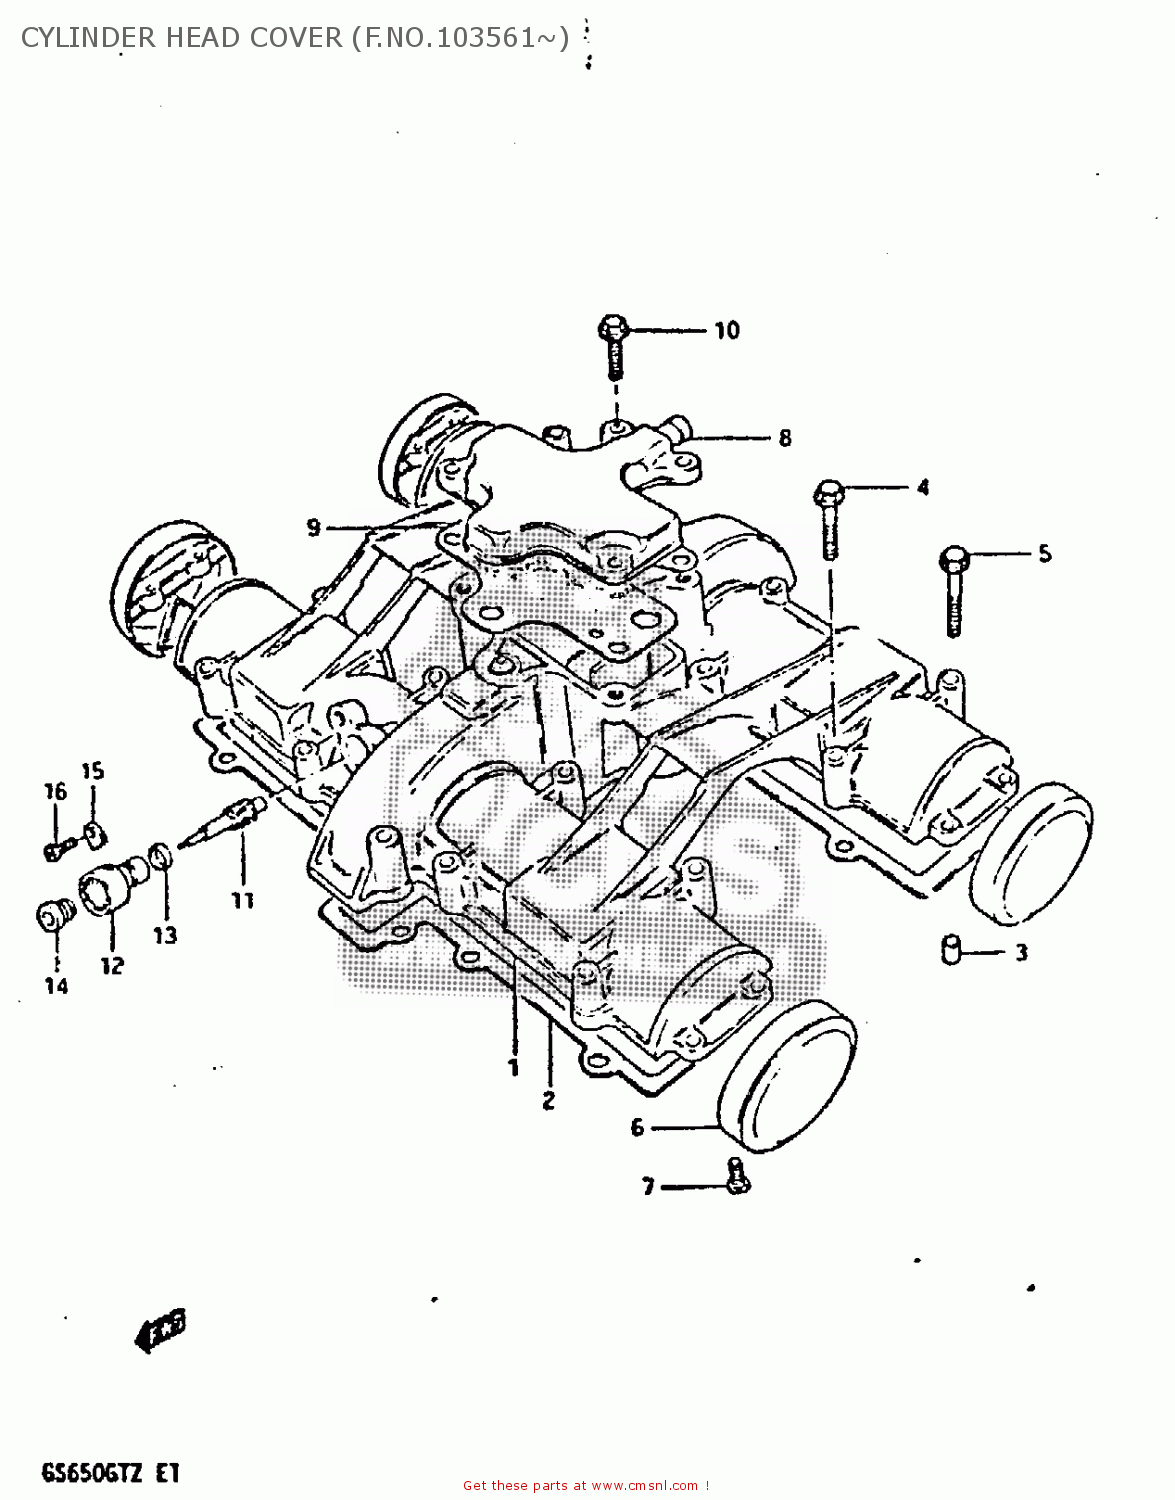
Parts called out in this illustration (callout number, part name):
1	COVER,CYLINDER HEAD
2	GASKET,CYLINDER HEAD COVER (MCA)
3	PIN(6.2X8X11)
4	BOLT
5	BOLT,UNDER
6	CAP,CYLINDER HEAD COVER
7	SCREW
8	COVER,BREATHER
9	GASKET (MCA)
10	BOLT,REAR
11	GEAR,TACHOMETER DRIVEN
12	SLEEVE,TACHOMETER DRIVE
13	SEAL,TACHOMETER DRIVEN
14	SEAL,OIL(5X12X8)
15	PLATE,TACH DRIVE GEAR SLEEVE
16	SCREW(5X12)
